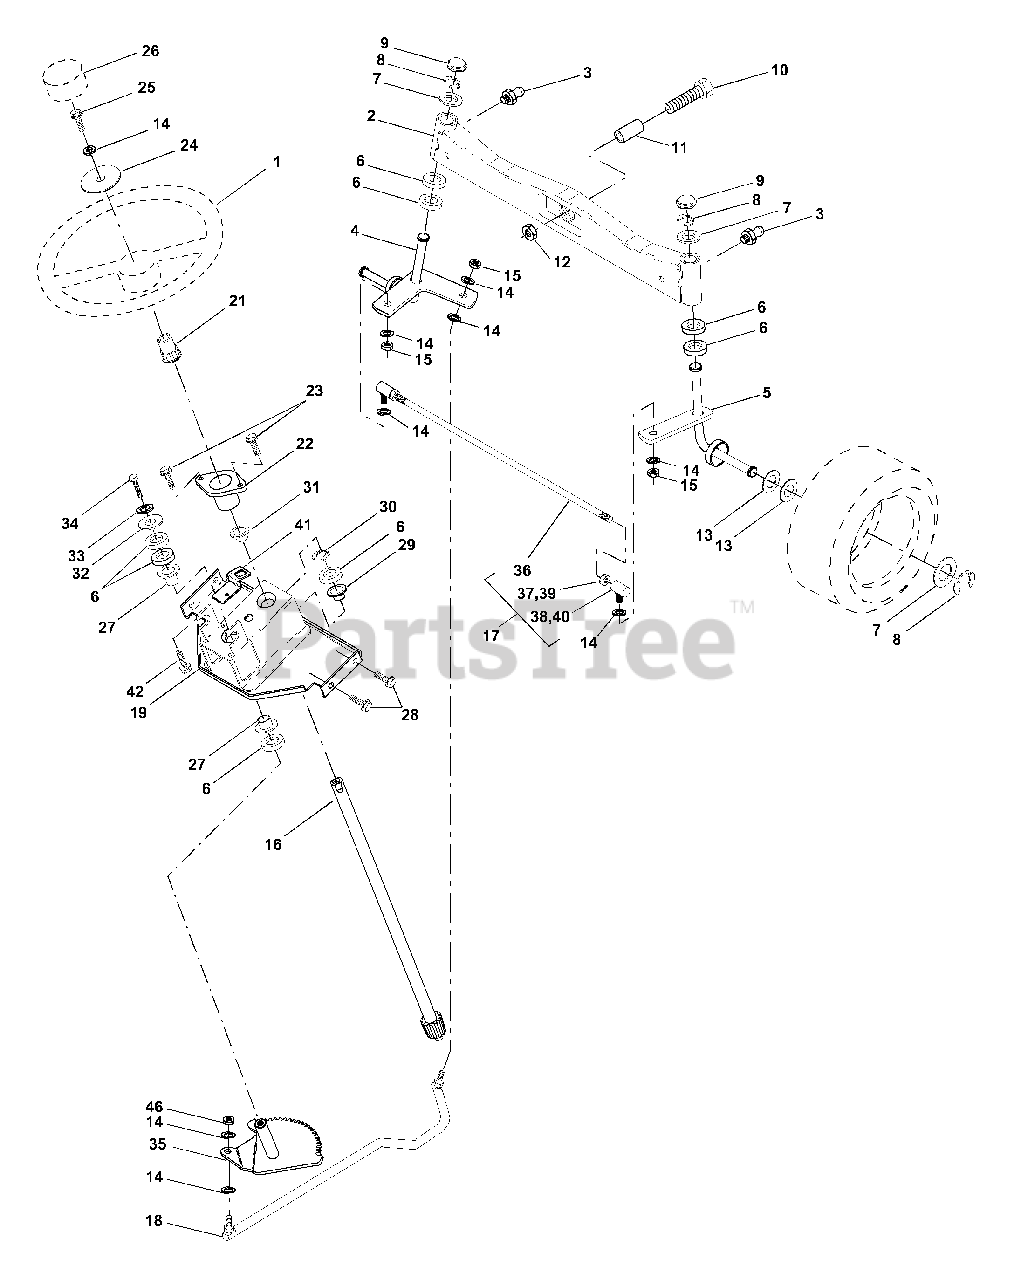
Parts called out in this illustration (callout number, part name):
1	Wheel, Steering
2	Axle Asm., Front
3	Fitting, Grease
4	Spindle Asm, LH
5	Spindle Asm., RH
6	Bearing, Race Thrust Harden
7	Washer 25/32 x 1-5/8 x 16 Ga.
8	Ring, Klip #T5304-75
9	Cap, Spindle
10	Bolt, Fin Hex 5/8-11 x 2-3/4
11	Spacer, Brg. Axle Front
12	Nut, Lock Flange 5/8-11 Unc
13	Washer 25/32 x 1-1/4 x 16 Ga.
14	Washer, Lock Hvy Hlcl Spr 3/8
15	Nut, Lock Center 3/8-24 Unf
16	Shaft Asm., Steering
17	Rod Asm., Tie Ball J Ball Vgt
18	Draglink, Ball Joint Solid Vgt
19	Support Asm., Steering Vgt
21	Adapter, Wheel Steering
22	Bushing, Strg.
23	Screw
24	Washer 13/32 x 1-1/20 x 11 Ga.
25	Bolt, Fin Hex 3/8-16 x 1 Gr. 5
26	Cap , Wheel Steering
27	Bearing, Col. Strg.
28	Screw 3/8-16 x 3/4
29	Bearing, Flange
30	Ring, Klip Truarc #5304-75
31	Bushing, Nyliner Snap
32	Washer 11/32 x 1 x 10 Ga.
33	Washer, Lock Hvy Hlcl Spr 5/16
34	Bolt, Hex Hd 5/16-18 x 3/4
35	Gear, Sector Steering
36	Tie Rod
37	Jam Nut RH Thread
38	Joint Asm. Ball RH Thread
39	Jam Nut LH Thread
40	Joint Asm. Ball LH Thread
41	Bracket Switch Interlock VGT 97
42	Screw Thdrol 5/16-18 x 1/2 TYT
46	Nut Lock Center 3/8-24 Unf
